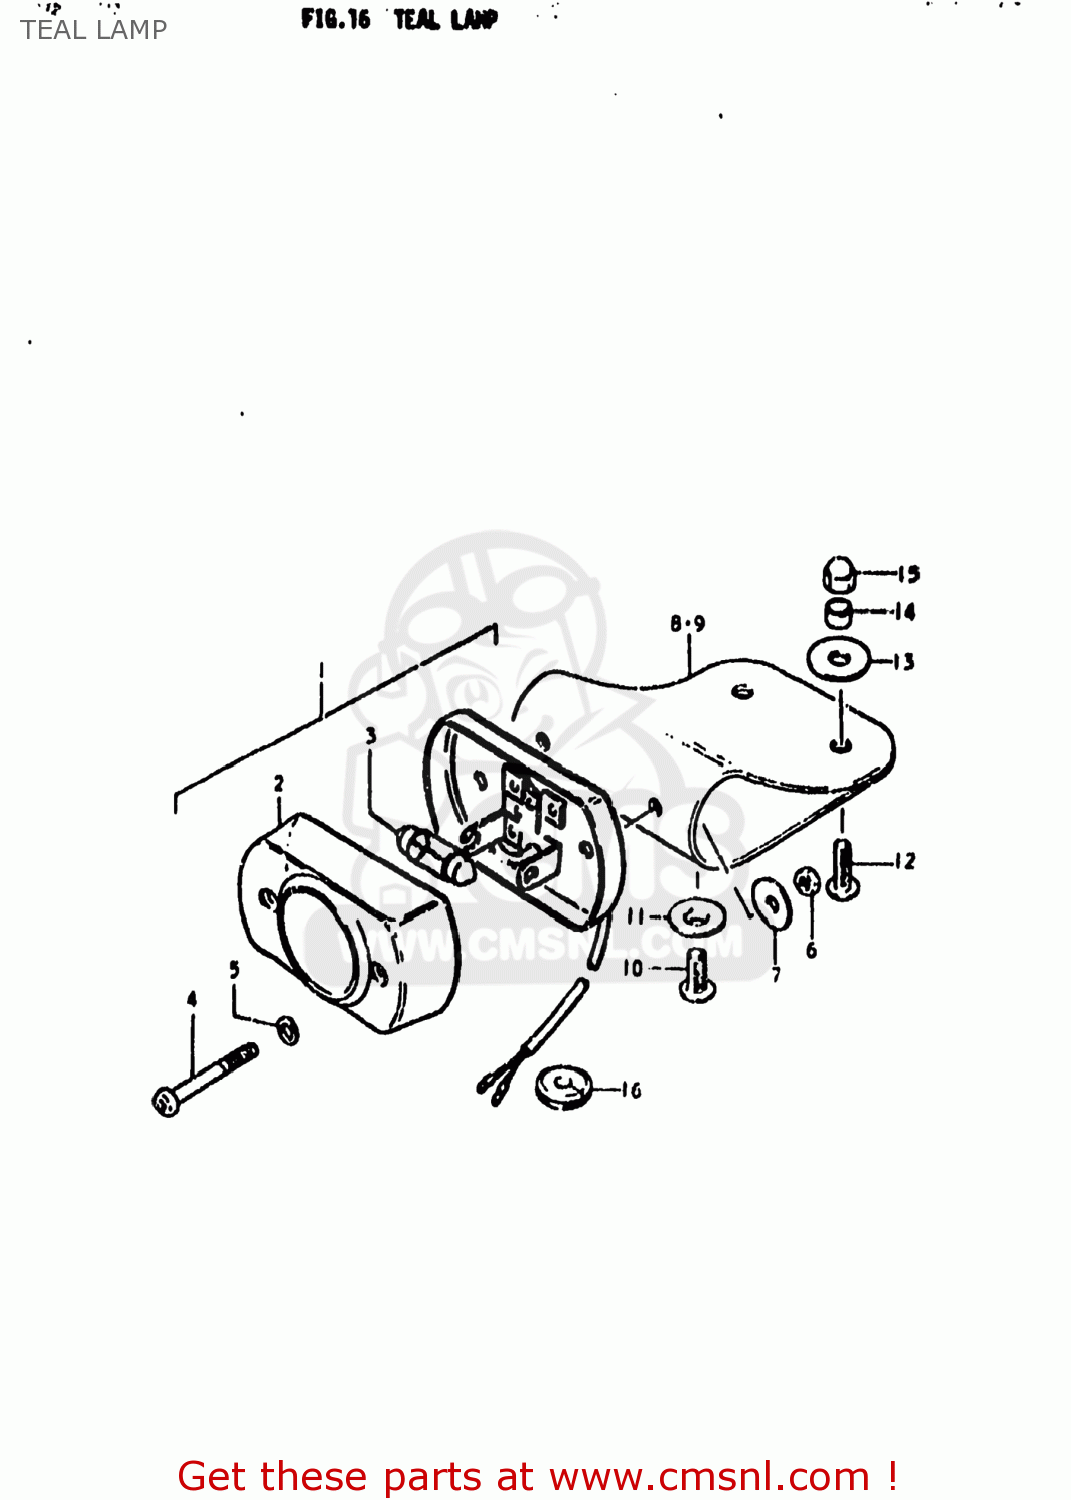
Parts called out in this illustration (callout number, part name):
1	LAMP ASSEMBLY,REAR COMBINATION
2	LENS,REAR COMBINATION LAMP
3	BULB
4	SCREW,REAR COMBINATION LAMP LENS
5	WASHER,REAR COMBINATION LAMP
6	NUT
7	WASHER(5.2X16X1)
8	CUSHION,REAR COMBINATION LAMP
9	CUSHION,REAR COMBINATION LAMP
10	SCREW 6X12
11	WASHER
12	SCREW
13	WASHER (6.5X20X1.2)
14	SPACER(6.2X8.3X5.7)
15	NUT
16	GROMMET
